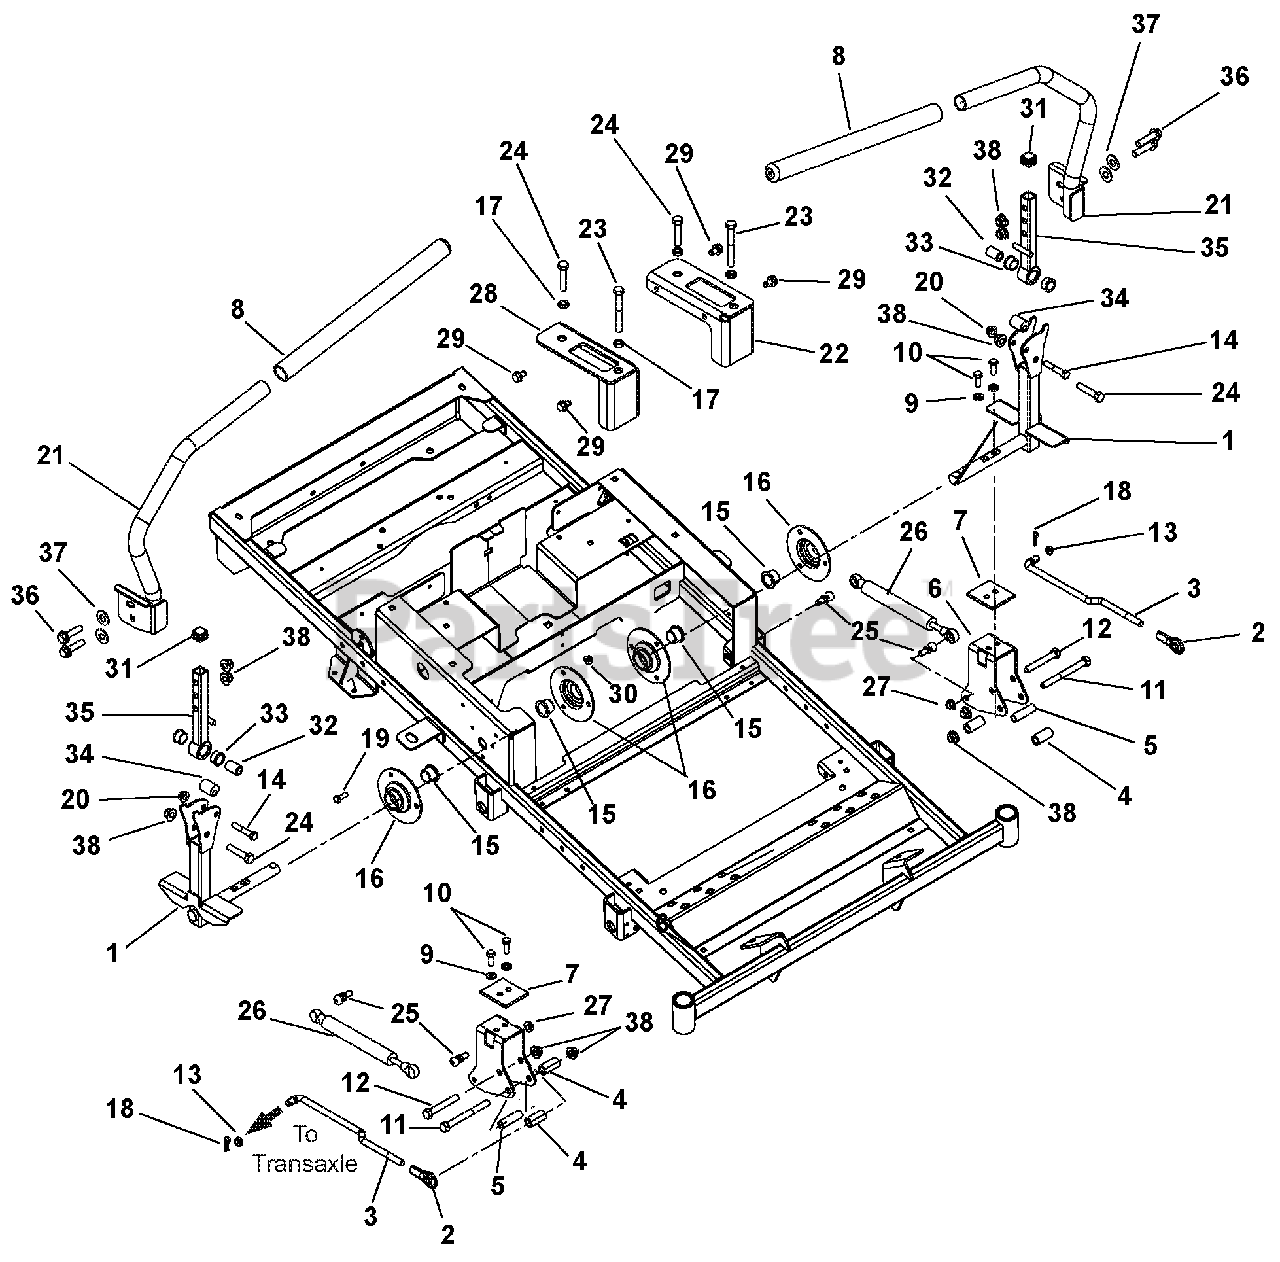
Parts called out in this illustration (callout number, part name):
1	Weldment, Control Arm
2	Rod End, .38 Right Hand
3	Link, Transmission
4	Bushing, Spacer .390 x .625 x 1.25 Promaster
5	Spacer, Steering
6	Bracket, Steering
7	Plate, Steering Reinforcing
8	Grip, Handlebar 15" Foam
9	Washer, Locking .31 x .078
10	Bolt, Hex .31-18 x 1.00 Grade 8
11	Bolt, Hex .38-16 x 3.75 Grade 5
12	Bolt, Hex .38-16 x 2.50 Grade 5
13	Bushing, Polyliner 322-C
14	Bolt, Hex .31-18 x 1.75 Grade 5
15	Bushing, Flange .750 x 1.000 x .625 x 1.250
16	Bearing Flange
17	Nut, Hex Jam .375-16
18	Pin, Hair Internal .08 x .18 x 1.18
19	Bolt, Hex .25-20 x .75 Grade 5
20	Nut, .31-18 Nyloc Flange
21	Weldment, Steering Handle Right Hand
21	Weldment, Steering Handle Left Hand
22	Bracket, Left Hand Speed Control
23	Bolt, Hex .38-16 x 3.00 Grade 5
24	Bolt, Hex .375-16 x 1.750 Full Thread
25	Stud, Ball
26	Damper, Control
27	Nut, Locking Top Flange .31-18
28	Bracket, Right Hand Speed Control
29	Screw, Tapping .31-18 x .50 Hex Washer Head
30	Nut, Locking Top Flange .25-20
31	Cap Plug, Square .75-14-20 Ribbed
32	Spacer, .375 x .625 x .970 (PM)
33	Bushing, Flange, .625 x .750 x .450 x .875
34	Bushing, Eccentric .31 x .75 x .97
35	Weldment, Upper Control Arm
36	Bolt, Serrated Hex Flange Washer Head .375-16 x 1.25
37	Washer, Flat Steel .406 x .812 x .065
38	Nut, Locking Center Jam .375-16
